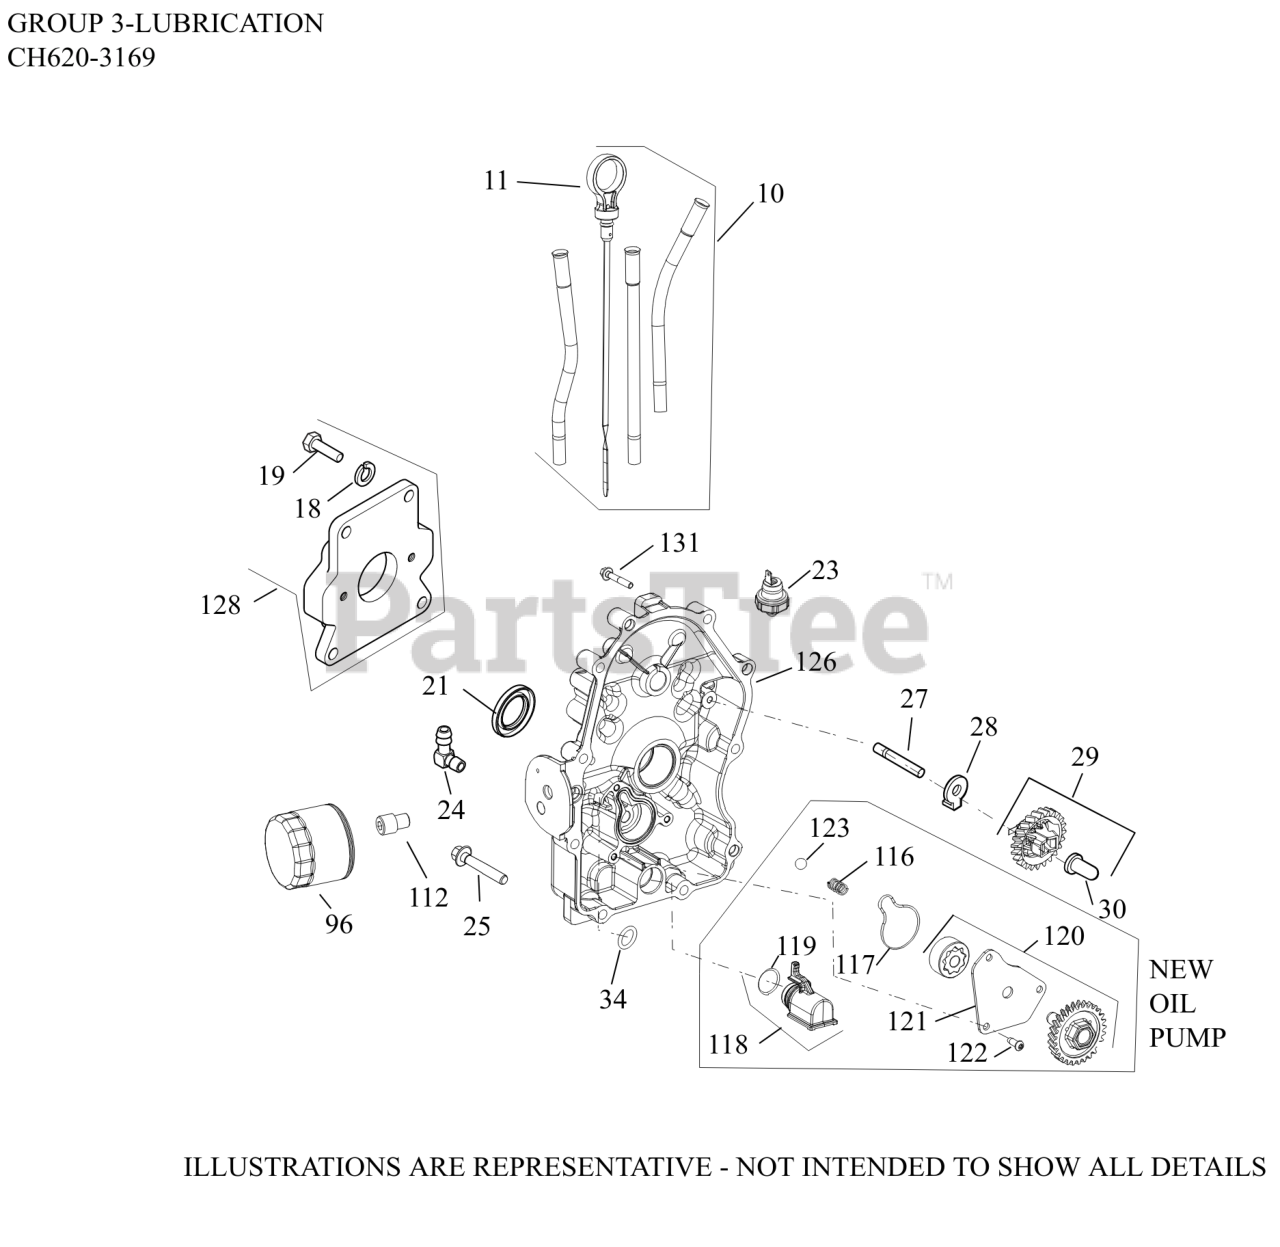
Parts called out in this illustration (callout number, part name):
10	KIT, DIPSTICK/DIPSTICK TUBES
18	WASHER, SPRING LOCK 7/16"
19	SCREW,CAP HD 7/16-14x1 1/2"
23	SENSOR, OIL PSI
24	CONNECTOR, 90 DEG. HOSE
25	SCREW, FLG M8X1.25X45
27	SHAFT, GOVERNOR GEAR
28	TAB, LOCKING
29	KIT, GOVERNOR GEAR W/PIN
30	PIN, GOVERNOR REGULATING
96	OIL FILTER
112	NIPPLE, OIL FILTER
116	SPRING, COMPRESSION
117	SEAL, OIL PUMP COVER
118	PICK-UP ASSEMBLY, OIL
119	O-RING, OIL PICK-UP
120	PUMP ASSEMBLY, OIL
121	COVER, OIL PUMP
122	SCREW, BUTTON HEAD
123	PRESSURE RELIEF BALL
126	KIT, CLOSURE PLATE ASSY
128	KIT, PUMP ADAPTER
131	SCREW, HEX FLANGE
